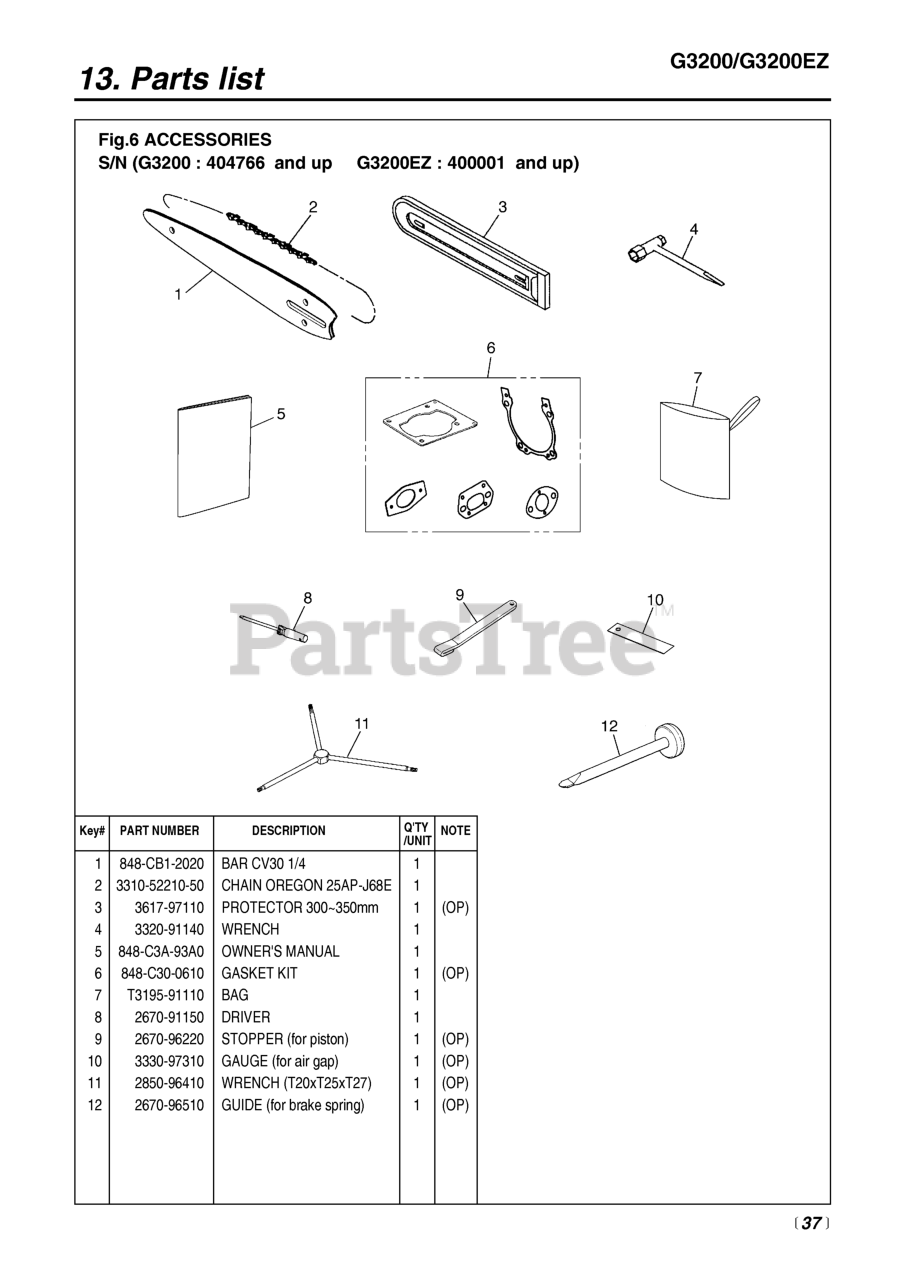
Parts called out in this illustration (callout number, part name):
1	BAR CV30 1/4
2	CHAIN OREGON 25AP-J68E
3	PROTECTOR (14.5
4	WRENCH, PLUG
6	GASKET KIT
8	SCREWDRIVER
9	STOPPER (TOOL)
10	GAUGE (TOOL)
11	WRENCH (RPLS. 2670-96410)
12	GUIDE (TOOL)
